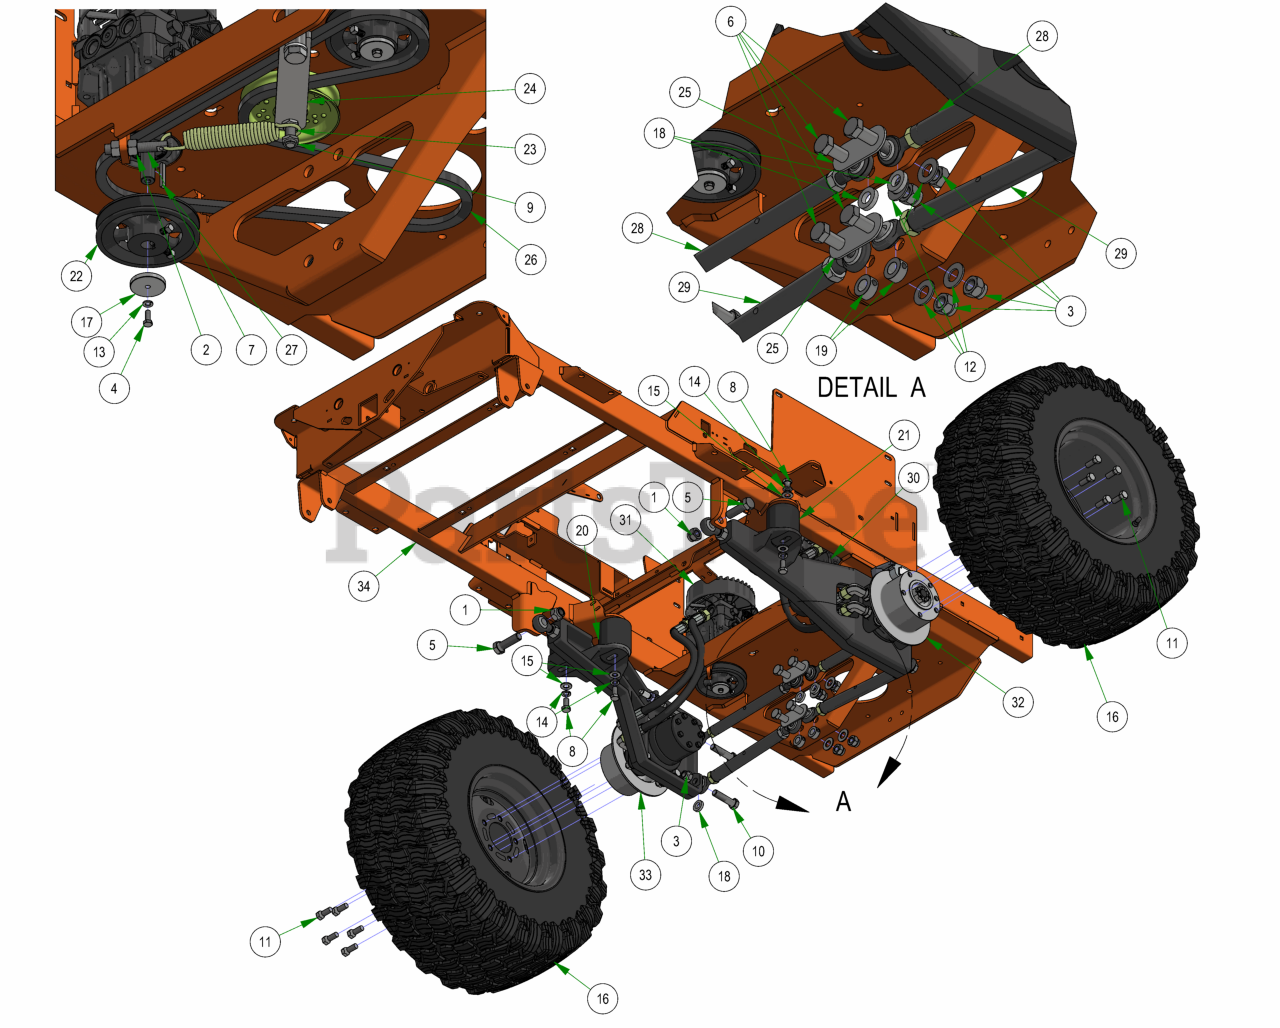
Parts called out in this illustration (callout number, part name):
1	3/4-10 NYLON INSERT LOCKNUT ZINC
2	1/2-13 HEX NUT ZINC
3	5/8-11 NYLON INSERT LOCKNUT ZINC
4	M6-1.0 X 16MM DIN 933 HEX TAP BOLT (CL 8.8) ZINC
5	3/4-10 X 2-1/2 HEX CAP SCREW (GR.5) ZINC
6	5/8-11 X 2-3/4 HEX CAP SCREW (GR.5) ZINC
7	All Thread
8	1/2-13 X 1 HEX CAP SCREW (GR.5) ZINC
9	1/2-13 NYLON INSERT JAM LOCKNUT ZINC
10	5/8-11 X 2-1/2 HEX CAP SCREW (GR.5) ZINC
11	1/2-20 x 60° Lug Bolts Zinc Grade 8
12	5/8" Flat Washer SAE Spec Grade 8
13	1/4 SPLIT LOCKWASHER ZINC
14	1/2 SPLIT LOCKWASHER (GR.8) ZINC/YELLOW
15	1/2 SAE FLAT WASHER (1-1/16" OD) GR.8 ZINC YELLOW
16	2019 Assy-26x12-12 Reaper Turf -10.5" Rim
17	Rogue Pump washer
18	Spacer 1.125OD x .625 ID x .250 Length
19	5/8 SOLID SHAFT COLLAR (W/1 SET SCREW) ZINC
20	Vibration Mount-Blue Dot
21	Vibration Mount-Green Dot
22	5" PUMP PULLEY W/ SET SCREW
23	Deck Idler Spring
24	2019 Rogue Pump Idler Assy
25	2019 Suspension Gusset Outlaw
26	2019 Rogue Pump Belt 68"
27	5MM X 36MM SQ MACHINERY KEY C1018 ROUNDED ENDS
28	2019 Suspension Radius Rod Assembly
29	2019 Suspension Radius Rod Assembly
30	2021 LH ROGUE HYDRO TANK LINE ASSY
31	2021 RH ROGUE HYDRO TANK LINE ASSY
32	2019 Rouge Trailing Arm LH Assy
33	2019 Rogue Trailing Arm RH Assy
34	2023 Rogue Frame - Painted
